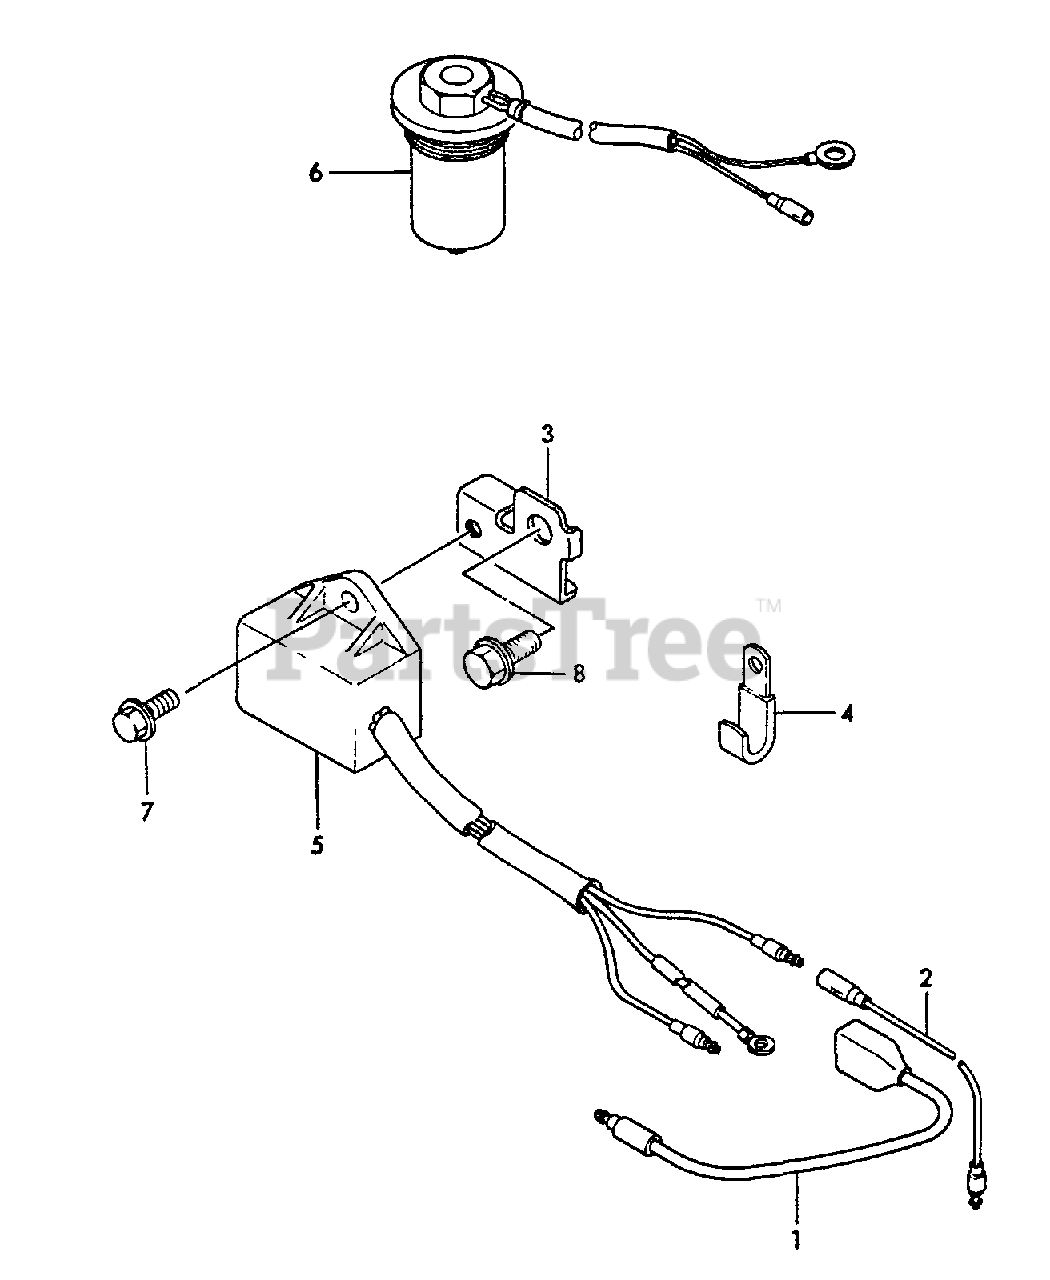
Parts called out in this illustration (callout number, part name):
1	WIRE
2	WIRE
3	STAY, SENSOR UNIT
4	CLAMP
5	SENSOR UNIT
6	SENSOR, OIL LEVEL
7	BOLT - 6×12 -- PLATED
8	BOLT - 8×14 -- PLATED
